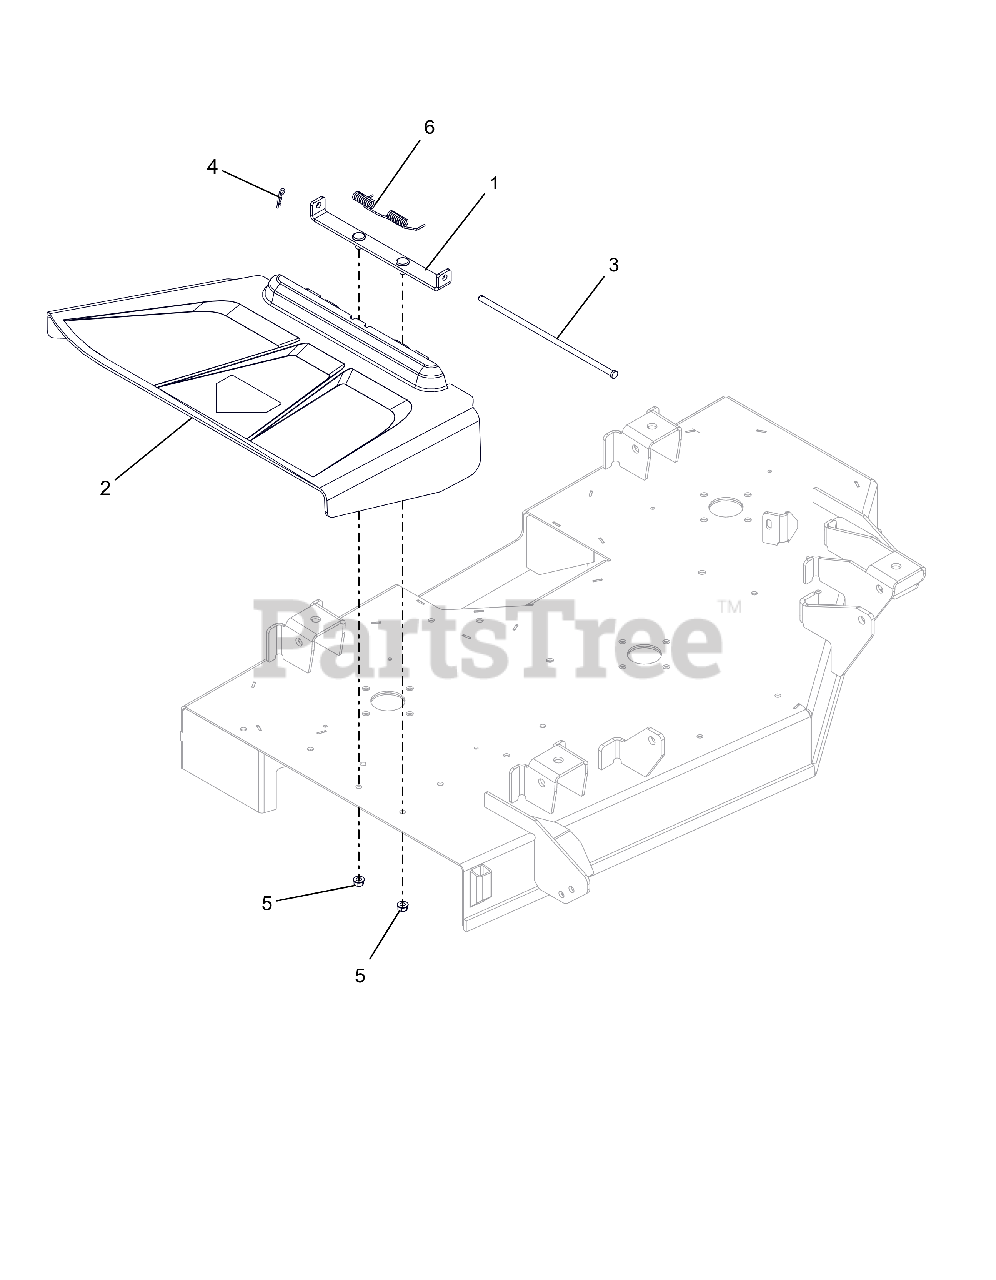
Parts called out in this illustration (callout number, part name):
1	WLDMT, CHUTE MT BRKT
2	CHUTE, SIDE DISCHARGE
3	PIN, 5/16 X 10.5
4	PIN, HAIR #213 .08X1.19 ZCC
5	NUT-LK-TOP-FLG .312-18 GF ZCC
6	SPRING-TORSION
